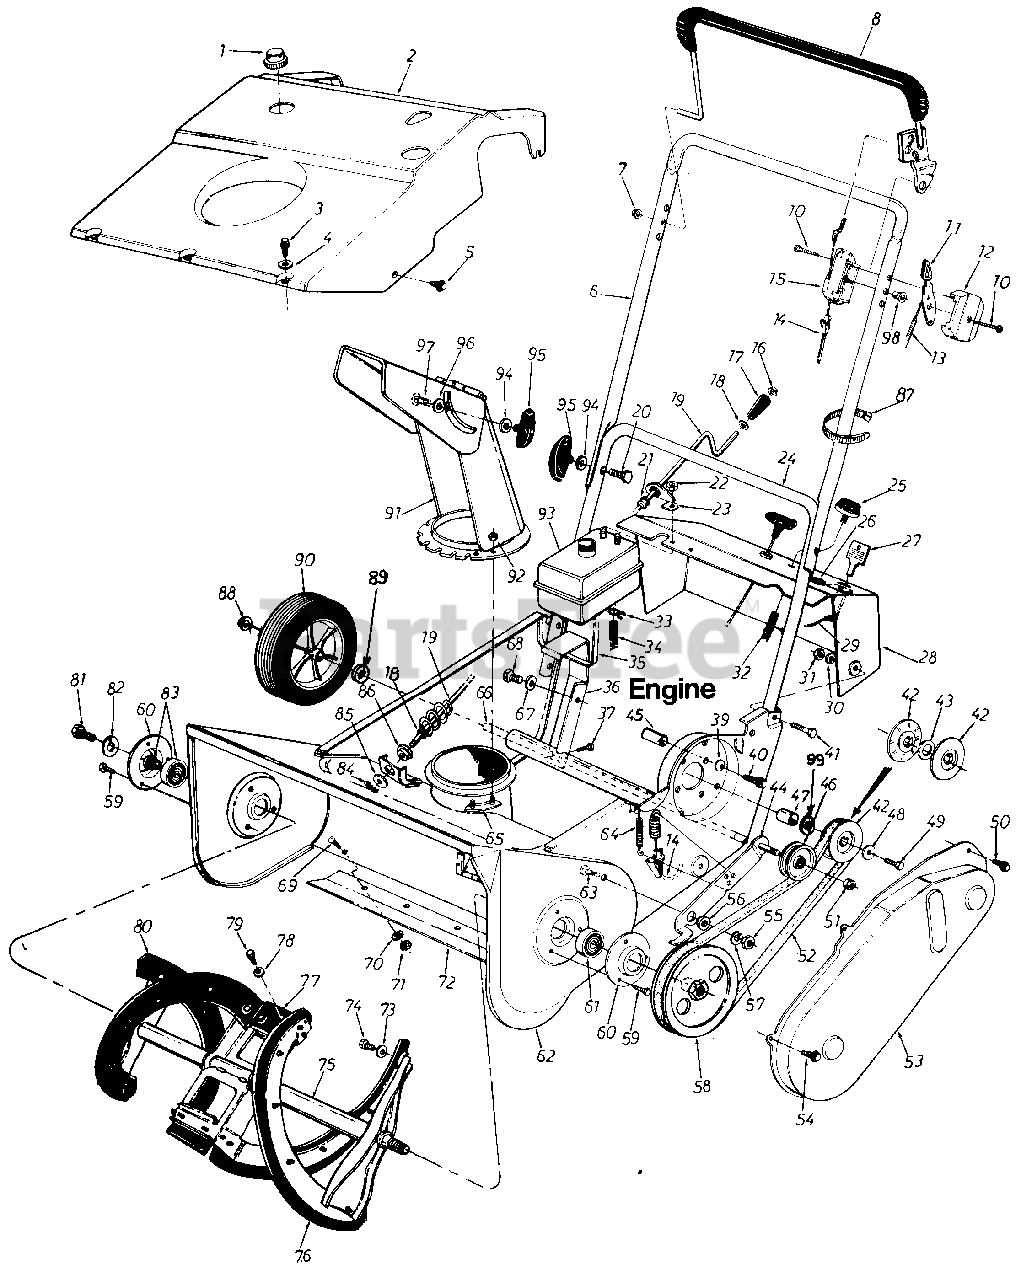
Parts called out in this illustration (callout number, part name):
1	Gas Tank Cap
2	21" Shroud
3	Hex B-Tap Scr. #10 x .38" Lg.
4	Spr.-Wash. .206" I.D. x .448" O.D.
5	Hex L-Wash. Hd. AB-Tap 1/4 x.62" Lg.
6	Upper Handle-Chrome
7	Cap Speed Nut
8	Control Handle Ass'y.-L.H.
10	Truss Mach. Hi-B Tap Scr. #12 x 1.5" Lg.
11	Throttle Lever
12	Control Panel Half
13	Throttle Wire-35"
14	Clutch Cable 35" Lg.
15	Clutch Panel Half
16	Push Cap 3/8" Rod
17	Knob-3/8" Dia. Hole
18	Fl-Wash. .385" I.D. x .62" O.D.
19	Chute Crank Ass'y.
20	Curved Carriage Bolt 5/16-18 x 1.75" Lg.
21	Chute Crank G rommet
22	Hex L-Nut 1/4-20 Thd.
23	Upper Chute Crank Brkt.
24	Lower Handle-Chrome
25	Primer
26	Plastic Plug-1-1/4"
27	Plastic Key
28	Dash Panel Ass'y.
29	Ignition Wire
30	L-Wash. 5/16" I.D.
31	Hex Nut 5/16-18 Thd.
32	Primer Hose-11 " Lg.
33	Hose Clamp-.406" Dia.
34	Gas Line-9" Lg.
35	Cable Tie-17.75" Lg.
36	Engine Support Brkt.
37	Hex L-Wash. Hd. AB-Tap Scr. 1/4 x.62" Lg.
39	Bell-Wash. .345" I.D. x .88" O.D.
40	Hex Bolt 5/16-18 x 1.5" Lg.
41	Hex Bolt 5/16-18 x 1.5" Lg.
42	3/8" "V"-Pulley Half .625" I.D. x 6.0" O.D.
43	Fl-Wash. .635" I.D. x .93" O.D.
44	Idler Brake Brkt. Ass'y.
45	Spacer.325" I.D. x .625" O.D. x .875"
46	Fl-Idler w/Flanges 2.12" O.D.
47	Spacer .635" I.D. x .89" O.D. x .57"
48	Bell-Wash. .345" I.D. x .88" O.D.
49	Hex Bolt 5/16-24 x .75" Lg.
50	Hex L-Wash. Hd. AB-Tap Scr. 1/4 x.62" Lg.
51	Hex Patch L-Nut 3/8-24 Thd.
52	V"-Belt 1/2" x 35" Lg.
54	Hex B-Tap Scr. 1/4" x .38" Lg
55	Hex Nut 5/16-18 Thd.
56	Shld. Spacer .50" Dia. x .27" Lg.
57	L-Wash. 5/16" I.D.
58	1/2" V -Pulley 1/2-20 LH. x 6 O.D.
59	Hex B-Tap Scr. 1/4" x .38" Lg
62	21" Blower Hsg. Ass'y.
63	Truss Mach. Scr. 5/16-18 x .75 " Lg .
64	Extension Spring-.33" O.D. x 1.12" Lg.
65	Chute Flange Keeper Ass'y.
66	Wheel Axle Tubing
67	L-Wash. 1/4" I.D.
68	Hex Wash. S-Tap Scr. 1/4-20 x.50" Lg.
69	Carriage Bolt 1/4-20 x .62" Lg.*
70	Bell-Wash. .265" I.D. x .75" O.D.
71	Hex Nut 1/4-20 Thd.
72	Shave Plate
73	Fl-Wash. .281" I.D. x .50" O.D.
74	Hex Wash. B-Tap Scr. 1/4 x .62"
75	Auger Ass'y. 21"
76	Rubber Spiral-L.H.
77	Rubber Paddle
78	Fl-Wash. .218" I.D. x .62" O.D.
79	Hex Wash. B-Tap Scr. #10 x .62" Lg.
80	Rubber Spiral-R.H.
81	Hex Wash. TT-Tap Cl-Scr. 1/4-20 x .75" Lg.
82	L-Wash. 1/4" I.D.
83	Kit-Bearing and Collar
84	Cotter Pin 3/32" Dia. x .75"
85	Fl-Wash. .390" I.D. x 1.50" O.D.
86	Hex Bushing .385" I.D.
87	Cable Tie
88	Push Cap 1/2" Dia.
89	Fl-Wash. .510" I.D. x .75" O.D.
90	Wheel & Tire Ass'y. 6 x 1.5
91	5" Dia. Chute Assy.
92	Hex L-Nut 1/4-20 Thd.
93	Fuel Tank-Two Qt.
94	Bell-Wash. .345" I.D. x .88" O.D.
95	Knob Handle Assy.
96	Fl-Wash. .328" I.D. x .68" O.D.
97	Carriage Bolt 5/16-18 x .62" Lg.*
98	Control Disc Pin
99	Fl-Wash. .635" I.D. x 1.04" O.D.
